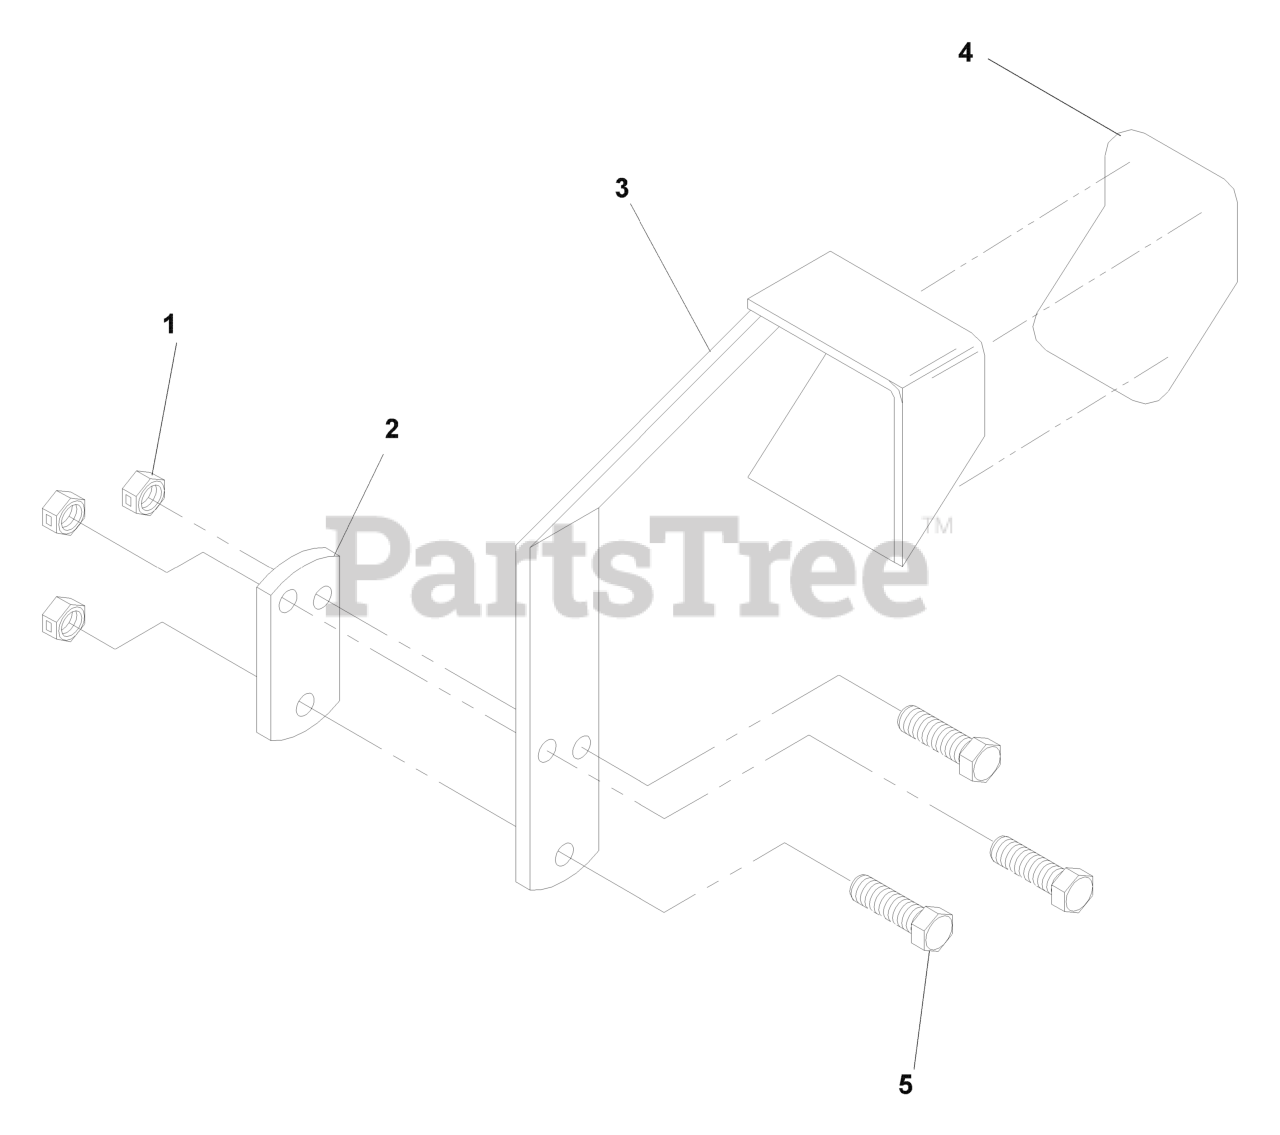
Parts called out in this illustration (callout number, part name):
1	NUT 3/8-16 NYLOC
2	TIGHTENING PLATE BLK
3	LIFT PEDAL BLK
4	ANTI-SKID PAD
5	HCS 3/8C X 1 1/2
